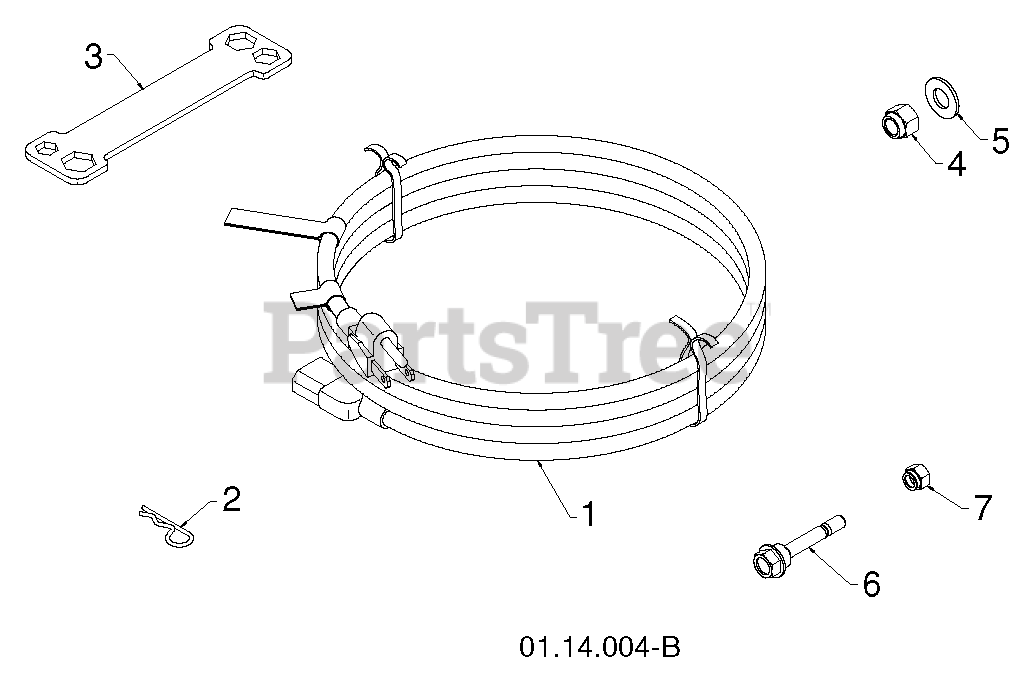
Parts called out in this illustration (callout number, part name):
1	CORD.ELECTRIC.10FT.120V.SNOW
2	SPRING RETAINER
3	WRENCH.SNOWTHROWER.ZINC.YZ
4	NUT
6	BOLT.SHOULDER.SHEAR.1/4-20.
7	LOCKNUT.NYLOC.1/4-20
